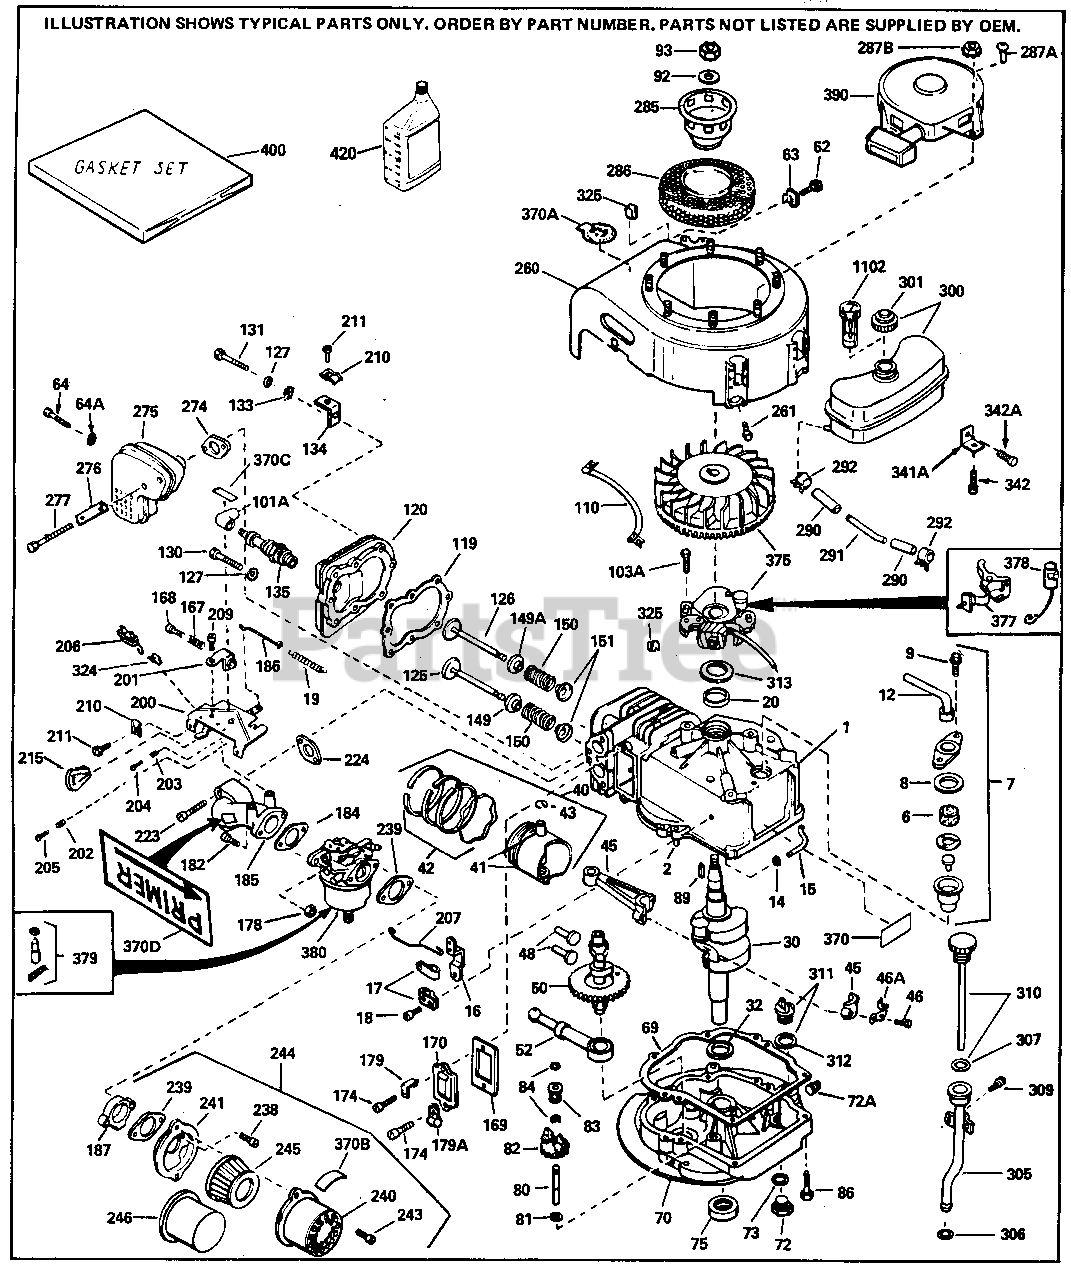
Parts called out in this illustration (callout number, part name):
1	"Cylinder (Incl. 2 & 20) 2-13/16" Bor e
2	Dowel Pin
6	Element, Breather
7	Breather Ass'y. (Incl. 6, 8, 9 & 12)
8	* Gasket, Breather
9	Screw, 10-24 x 9/16"
12	Tube, Breather
14	Flat Washer
15	Rod, Governor (Incl. 14)
16	Lever, Governor
17	Clamp, Governor Clamp is positioned t owardsspark plug end on 1977-78 and l atermodels. It is positioned opposite spark plugend on earlier models.
18	Screw, 8-32 x 5/16"
19	Spring, Governor
20	Seal, Oil
30	Crankshaft Ass'y.
32	Washer, Thrust NOTE: This thrust wash er maynot be required if a new cranks hafthas been installed. Check the pro per Mechanic's Handbook for acceptabl e end play. Use this .010" thrust was her if excess end play is measured.
40	Piston, Pin & Ring Set (Std.) 2-13/1 6"
40	Piston, Pin & Ring Set (.010" OS)
40	Piston, Pin & Ring Set (.020" OS)
41	Piston & Pin Ass'y. (Std)(Incl. 43) 2 -13/16"
41	Piston & Pin Ass'y. (.010" OS) Incl. 43
41	Piston & Pin Ass'y. (.020" OS) Incl. 43
42	Ring Set (Std.) (2-13/16" Bore)
42	Ring Set (.010" OS)
42	Ring Set (.020" OS)
43	Piston Pin Retaining Ring
45	Rod Assy., Connecting (Incl. 18)
46	Bolt, Connecting rod Early Productio n
46	Bolt, Connecting rod
46A	Plate, Lock Do not use with No. 32610 A locking type bolt.
48	Valve Lifter
50	Camshaft
52	Oil Pump Ass'y.
69	* Gasket, Mounting flange
70	Flange Ass'y. (Incl. 72, 75 & 80)
72	Plug, Oil drain (Incl. 73)
72A	Plug, Pipe
73	* Drain Plug Gasket Not used w/ plastic plug
75	Oil Seal
80	Shaft, Mechanical governor
81	Washer, Flat
82	Gear Assy., Governor (Incl. 81)
83	Spool, Governor
84	Retaining Ring
86	Screw, 1/4-20 x 1-1/4"
89	Key, Flywheel
92	Washer, Belleville
93	Nut, Flywheel
101A	Spark Plug Cover
103A	Screw, 1/4-20 x 5/8"
110	Wire, Ground
119	* Gasket, Cylinder head
120	Head, Cylinder (Incl. 131)
125	Intake Valve (Std.) (Incl. 151) (Inve rted Ports)
125	Intake Valve (1/32" OS) (Incl. 151) ( Inverted Ports)
126	Exhaust Valve (Std.) (Incl. 151) (Inv erted Ports)
126	Exhaust Valve (1/32" OS) (Incl. 151) (Inverted Ports)
127	Washer tion)
127	Washer, Flat (Use as required)
130	Screw, 5/16-18 x 1-1/2" Use as requir ed
131	Screw, 5/16-18 x 2" (Use as required)
135	Resistor Spark Plug - RJ17LM
149	Upper Cap (Int. & Ex.) Early Producti on
149A	Cap, Upper valve spring (Exhaust)
150	Spring, Valve
151	Cap, Lower valve spring
169	* Gasket, Valve spring cover
170	Cover, Valve spring box
174	Screw, 10-24 x 1/2"
178	Nut & Lock Washer 1/4-28
179	Clip, Magneto wire
182	Screw, 1/4-28 x 1"
185	Pipe, Intake
186	Link, Governor spring
200	Speed Control (Incl. 203, 204 & 206)
203	Spring, Compression
204	Screw, 5-40 x 7/16"
206	Terminal Assy. (Use as required)
207	Link, Throttle
209	Screw, 10-24 x 9/16"
210	Conduit Clip
211	Screw, 10-32 x 3/8"
223	Screw, 1/4-20 x 1-1/8"
224	* Gasket, Intake
238	Screw, 10-32 x 1/2"
239	* Gasket, Air cleaner
240	Body, Air cleaner
241	Bracket, Air cleaner
243	Screw, 8-32 x 3/8"
244	Cleaner Kit (Incl. 238 thru 245 & 370 B) (Use as required)
246	Air Filter
260	Housing, Blower NOTE: Replacement har dware may differ when servicing start er assy. or blower housing. Refer to Service Bulletin 508.
261	Screw, 1/4-20 x 5/8"
274	* Gasket, Exhaust (Use as required)
274	* Gasket, Exhaust
275	Muffler (Incl. 274)
277	Screw, 1/4-20 x 2-3/8"
277	Screw, T-30, 1/4-20 x 1/2"
285	Cup, Starter
286	Screen, Starter cup
287B	Nut & Lock Washer 1/4-28 red)
290	Fuel Line (8.62")
290	Fuel Line (Braided 16") (40 cm)
291	Line, Fuel (Metal 3.360")
292	Fuel Line Clamp
300	Tank Assy., Fuel (Incl. 292 & 301)
301	Fuel Cap (Red 1-1/2" ID) also availab le in Packaged Part #740005B
301	Cap, Fuel (Standard) Use as required
306	"O" Ring This "O" ring is required wi th metal fill tube only when replacem ent mounting flange with .777 dia. oi l fill hole has been used.
311	Oil Fill Plug (Incl. 312) also availa ble in Packaged Part #740079
312	* Gasket, Filler plug
313	Gasket, Stator
325	Wire Clip
325	Clip, Wire retaining Early Productio n
370	Decal, Instruction
370C	Throttle Decal
375	Magneto NOTE: The complete magneto is not available as an assembly. The ma gneto number is shown for reference p urposes only. Order component parts i ndividually, as shown in parts list. (Refer to Division 5, Section B, page 35 or Fiche 6 Grid F-13
377	Breaker Points (also available in Pac kaged Part #740037B)
378	Condenser (also available in Packaged Part #740037B)
379	Inlet Needle, Seat & Clip Assy.
380	Carburetor (Incl. 184) (Refer to Divi sion 5, Section A, page 122 or Fiche 6 Grid E-7 for breakdown)
390	Starter, Rewind NOTE: Replacement har dware may differ when servicing start er assy. or blower housing. Refer to Service Bulletin 508. (Refer to Divis ion 5, Section C, page 25 or Fiche 6, Grid G-3 for breakdown)
400	* Gasket Set (Incl. items marked *)
420	SAE 30, 4-Cycle Engine Oil (Quart)
